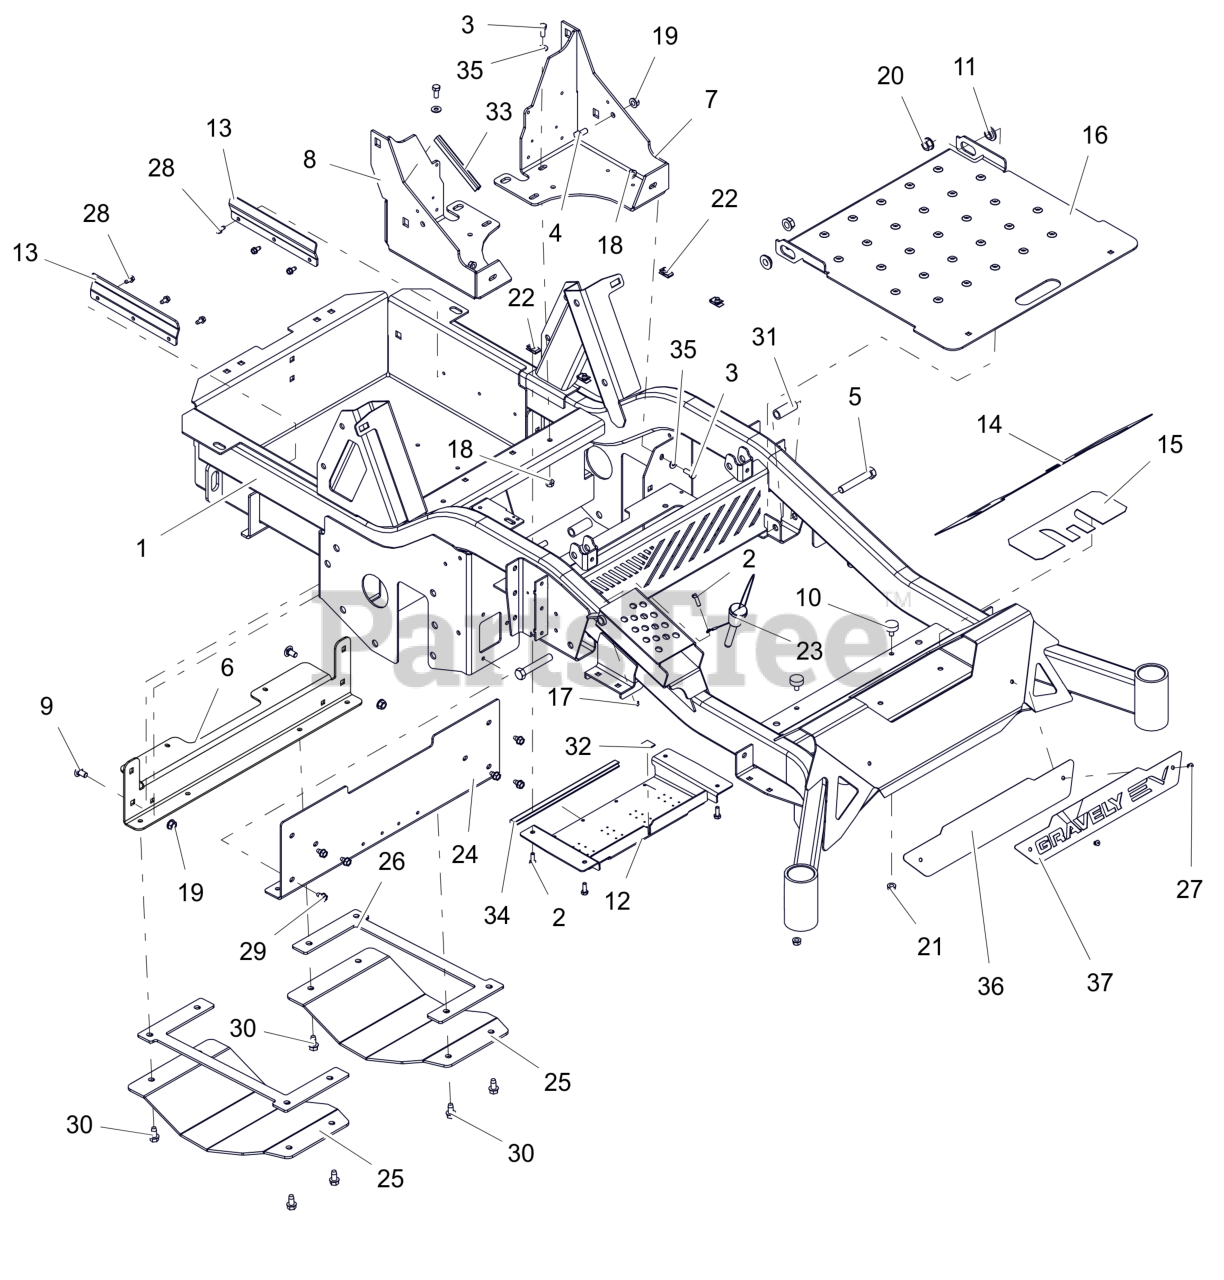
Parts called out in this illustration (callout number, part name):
1	KIT,EV FRAME(LG)W/DECALS-G
2	BLT, HEX .25-20X.75 G5 ZCC
3	BLT,HEX .31-18X.75 G5 ZCC
4	BLT,HEX .38-16X.75 G5 ZCC
5	BLT, HEX .50-13X3.00 G5 ZCC
6	BRKT, SKID PLATE MTG. (RED)
7	BRKT, SUPPORT ROPS -LH (RED)
8	BRKT, SUPPORT ROPS-RH (RED)
9	BLT, RHSSN .38-16X.75 G5 ZCC
10	BUMPER, RUBBER
11	BSHG-FLG .515X.750X.310X1.120
12	COVER, BOTTOM ACCESS -OPEN (RED)
13	DEFLECTOR, BATTERY -EV (RED)
14	GRIP, FRONT
15	GRIP, TAPE FRONT
16	KIT,ACCESS PANEL W/DECALS-RED
17	NUT-LK-CTR-FLG .25-20 ZC120
18	NUT,LK-CTR-FLG .31-18 GF ZCC
19	NUT-LK-CTR-FLG .375-16 GF ZCC
20	NUT-LK-CTR-FLG .500-13 GG ZCC
21	NUT,SPNLK-FLG .31-18 G5 ZCC
22	NUT-RTNR .25-20X.56
23	PIN, MAGNETIC .50X2.50
24	PLATE, FRONT FRAME (RED)
25	PLATE, SKID (BLACK)
26	PLATE, SKID TENSION (BLACK)
27	RIVET, .1875 AL/AL .126-.250
28	SCR-TAP .25-20X.50 HWH ZCC
29	SCR,TAP .312-18X.50 HWH TR ZCC
30	SCR,TAP .375-16X.75 HWH TR ZCC
31	SPACER, .515X.75X1.83
33	STRIP, COWL
34	STRIP, COWL
35	WSHR, FLT .312X.734X.065 ZCC
36	PLATE, BACK - GRAVELY (BLACK)
37	PLATE, LOGO - GRAVELY EV (RED)
